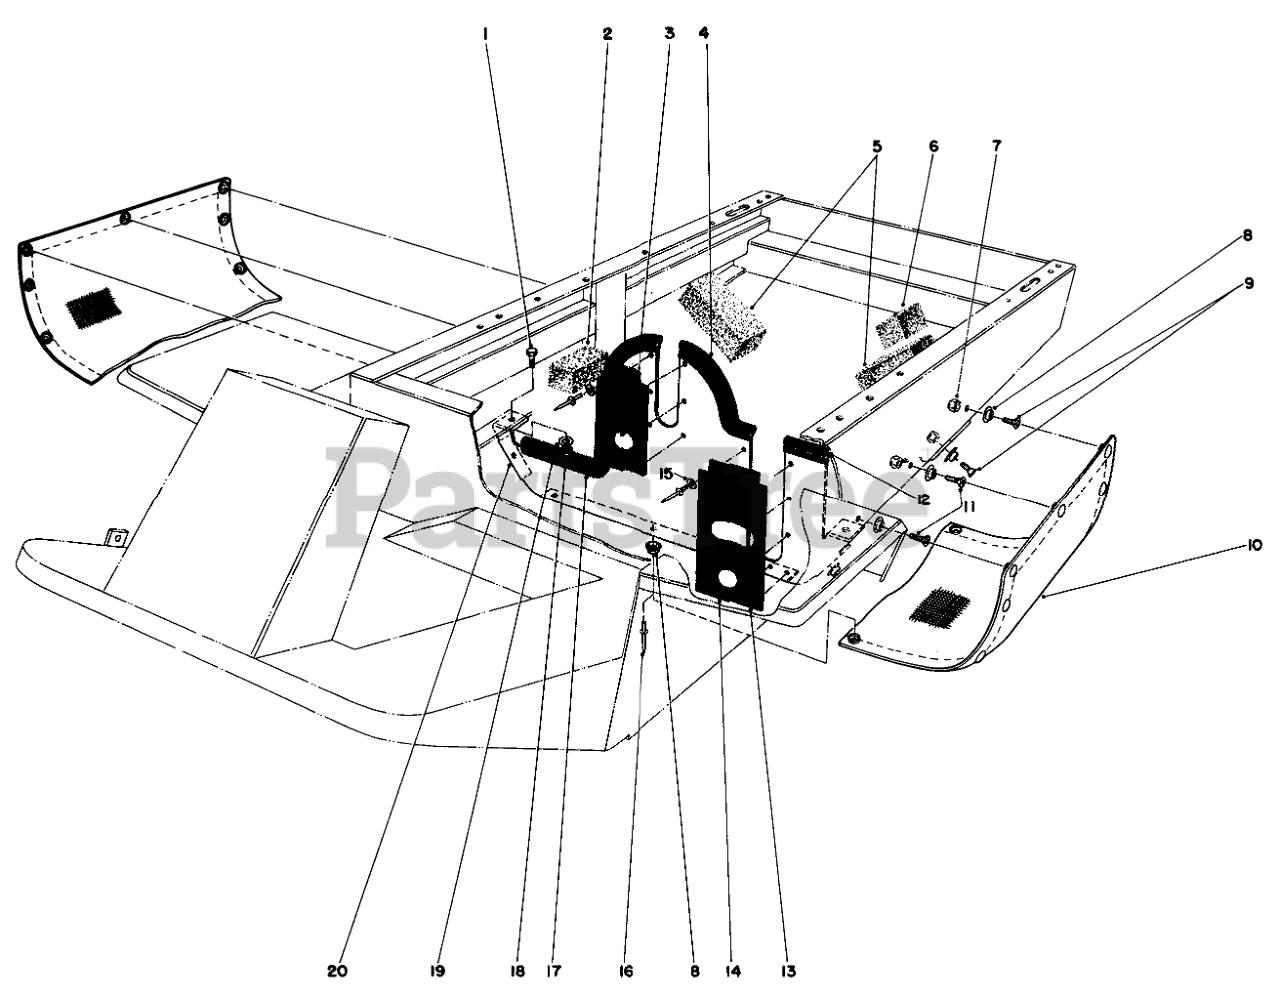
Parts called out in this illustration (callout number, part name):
1	SCREW-HH
2	SIDE FOAM
4	TRIM SEAL
5	REAR FOAM
6	LH REAR FOAM
7	NUT-HEX
8	SNAP STUD
9	6-32 X 5/8 FLAT HD SCR
10	GRASS SCREEN BAG
11	Self Tapping Screw
12	TRIM SEAL
13	LH FLAP
14	RH FLAP
15	WASHER
16	RIVET-POP
17	TRIM SEAL
18	NUT-HEX
19	WASHER-LOCK/SP
20	Shield Assembly Front (Incl. Ref. #3-4, 8, & 12-17)
